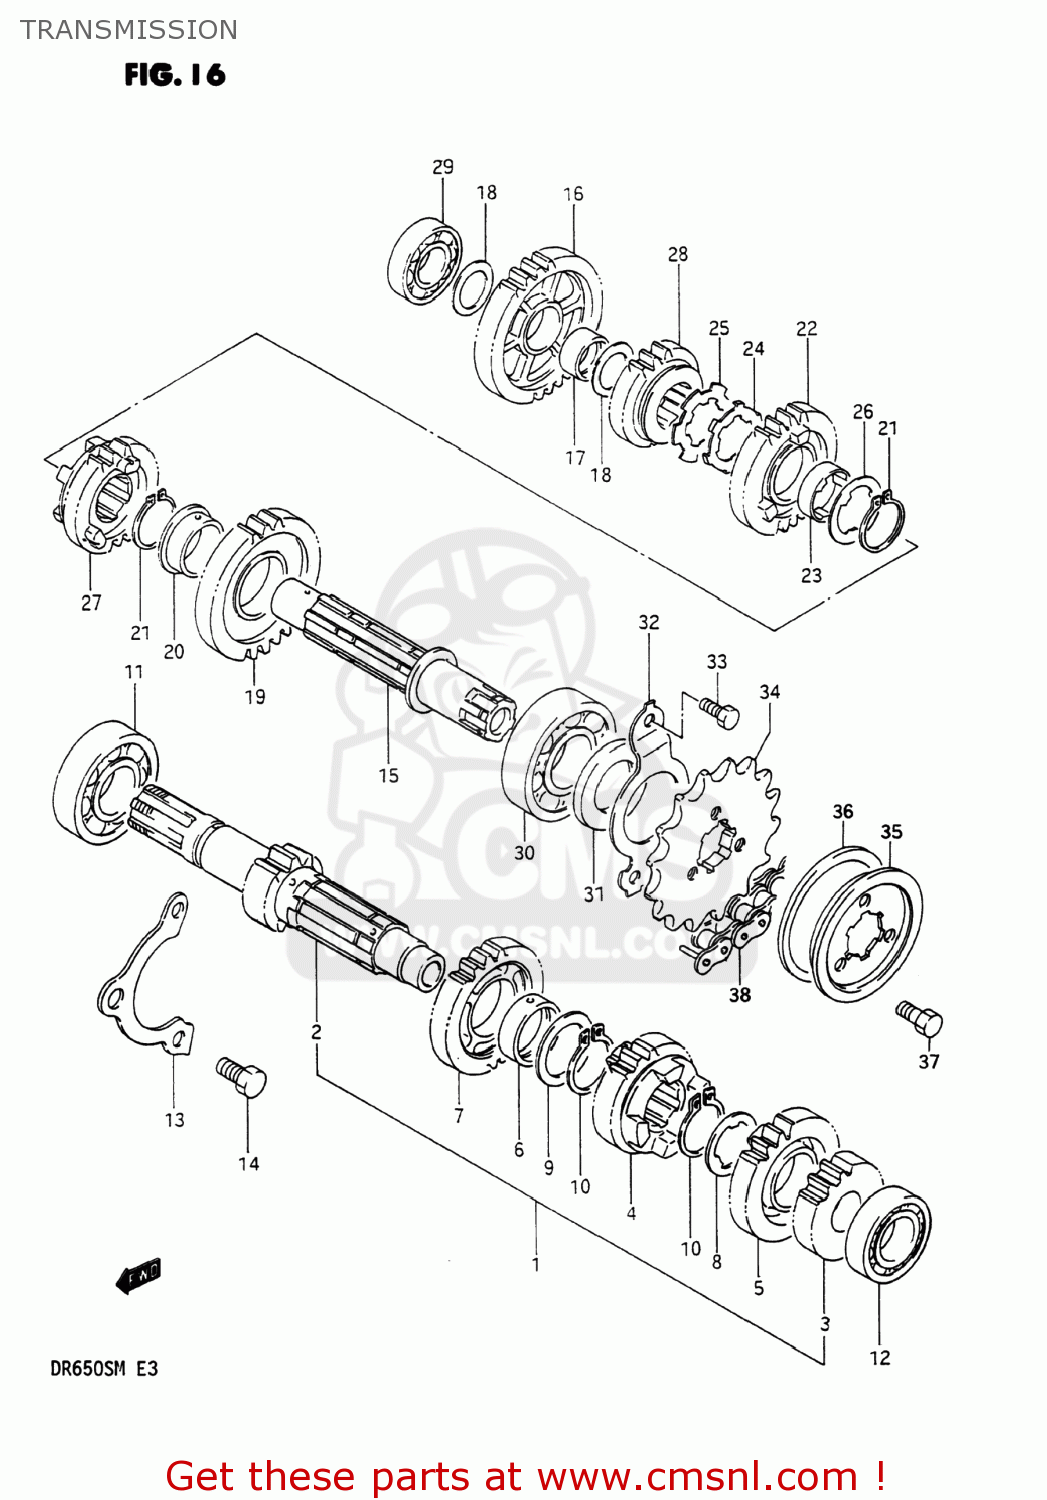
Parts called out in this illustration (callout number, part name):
1	SHAFT,COUNTER
2	SHAFT,COUNTER
3	GEAR,SECOND DRIVE
4	GEAR,THIRD DRIVE
5	GEAR,FOURTH DRIVE
6	BUSHING 25X29X10
7	GEAR,5TH DRIVE
8	WASHER,LOCK
9	WASHER
10	RING,SNAP
11	BEARING
12	BEARING
13	RETAINER,CNTR SHAFT BEARING
14	BOLT, 8X1.25X1
15	SHAFT,DRIVE
16	GEAR,1ST DRIVEN
17	BUSH(20X24X13)
18	WASHER
19	GEAR,2ND DRIVEN
20	BUSH
21	RING,SNAP
22	GEAR,THIRD DRIVEN
23	BUSHING
24	WASHER
25	WASHER,LOCK
26	WASHER,LOCK
27	GEAR,FOURTH DRIVEN
28	GEAR,FIFTH DRIVEN
29	BEARING(20X42X12)
30	BEARING(25X62X17)
31	SEAL,OIL(25X45X5)
32	RETAINER,DRIVESHAFT O
33	BOLT
34	SPROCKET,ENGINE(NT:16)
35	PLATE,ENGINE SPROCKET
36	DAMPER,ENGIN SPROCKET
37	BOLT(6X13)
38	CHAIN ASSEMBLY,DRIVE
